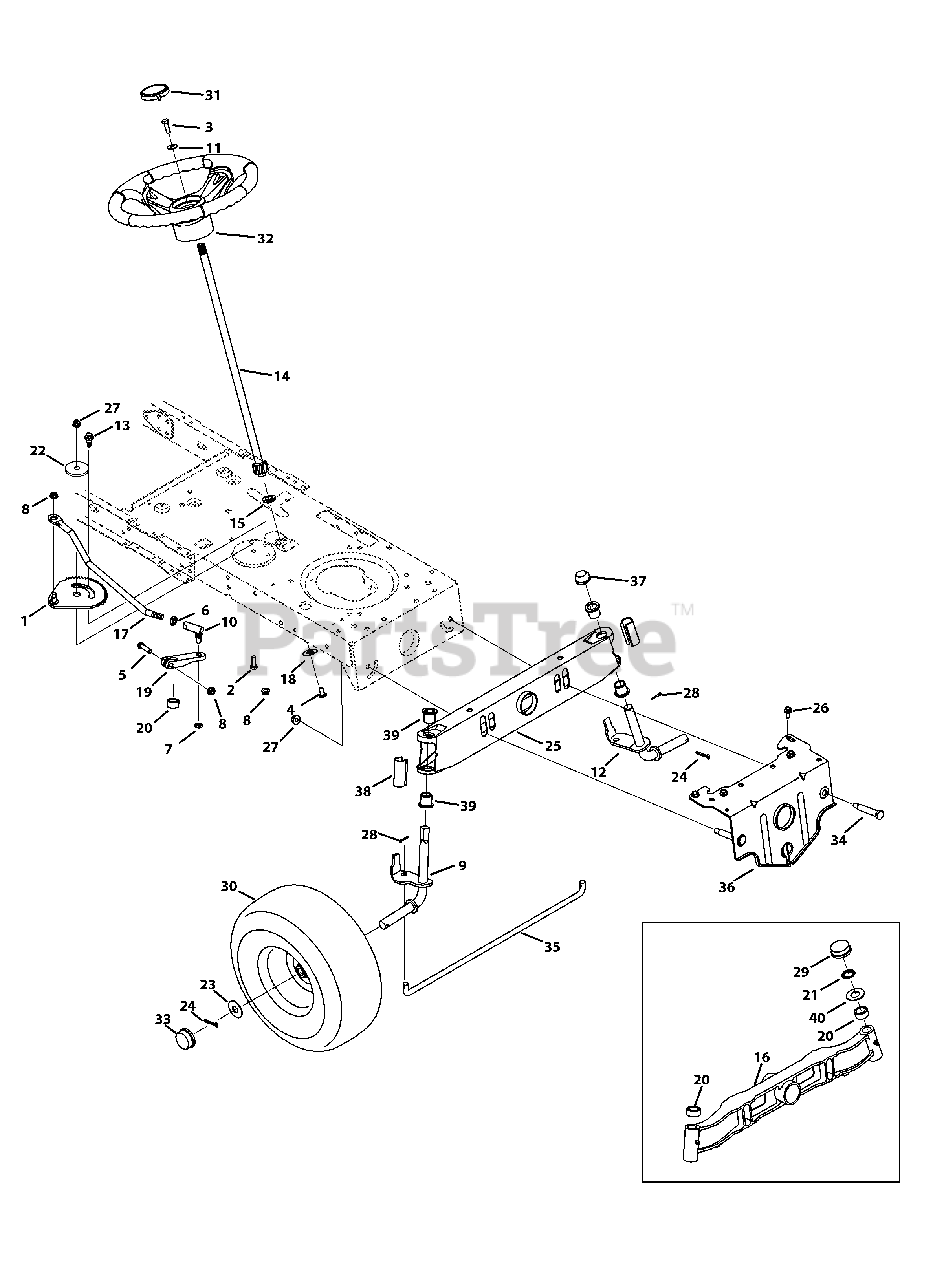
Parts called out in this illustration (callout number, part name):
1	Front Steering Gear Assembly
2	Hex Screw, 3/8-16 x 1.00
3	Hex Screw, 5/16-18 x 1.00, Lock
4	Machine Screw, 5/16-18 x .750
5	Hex Screw, 5/16-18 x 1.75
6	Jam Nut, 7/16-20
7	Jamlock Nut, 3/8-24
8	Flangelock Nut, 5/16-18
9	Front RH Axle
10	Ball Joint, 7/16-20
11	Bell Washer, .340 x .872 x .060
12	Front LH Axle
13	Shoulder Bolt, 5/16-18 x .435 x .350
14	Steering Shaft, 5/8 x 22.08
15	Flange Bearing, 5/8
16	Pivot Bar, Cast
17	Steering Link
18	Cap, 1.25 x .16
19	Steering Block
20	Spacer, .71 x .125 x .56
21	Push Nut 3/4 Dia.
22	Shoulder Spacer, .884 x .190
23	Flat Washer, .781 x 1.590
24	Cotter Pin, 5/32 x 1.25
25	Pivot Axle
26	Screw, 5/16-18 x .750
27	Flangelock Nut, 3/8-16
28	Cotter Pin, .125 x .75
29	Push Cap, Cast
30	Wheel Assembly, 46"
31	Sprig Cap
32	Steering Wheel
33	Hub Cap
34	Shoulder Bolt, 3/8-16 x .500 x 2.38
35	Fixed Rod
36	Pivot Bar Bracket
37	Push Cap, 3/4
38	Standard Axle Cap
39	Flange Bearing, .760 x .941 x 1.0
40	Washer, Flat, .78 x 1.59 x .60
